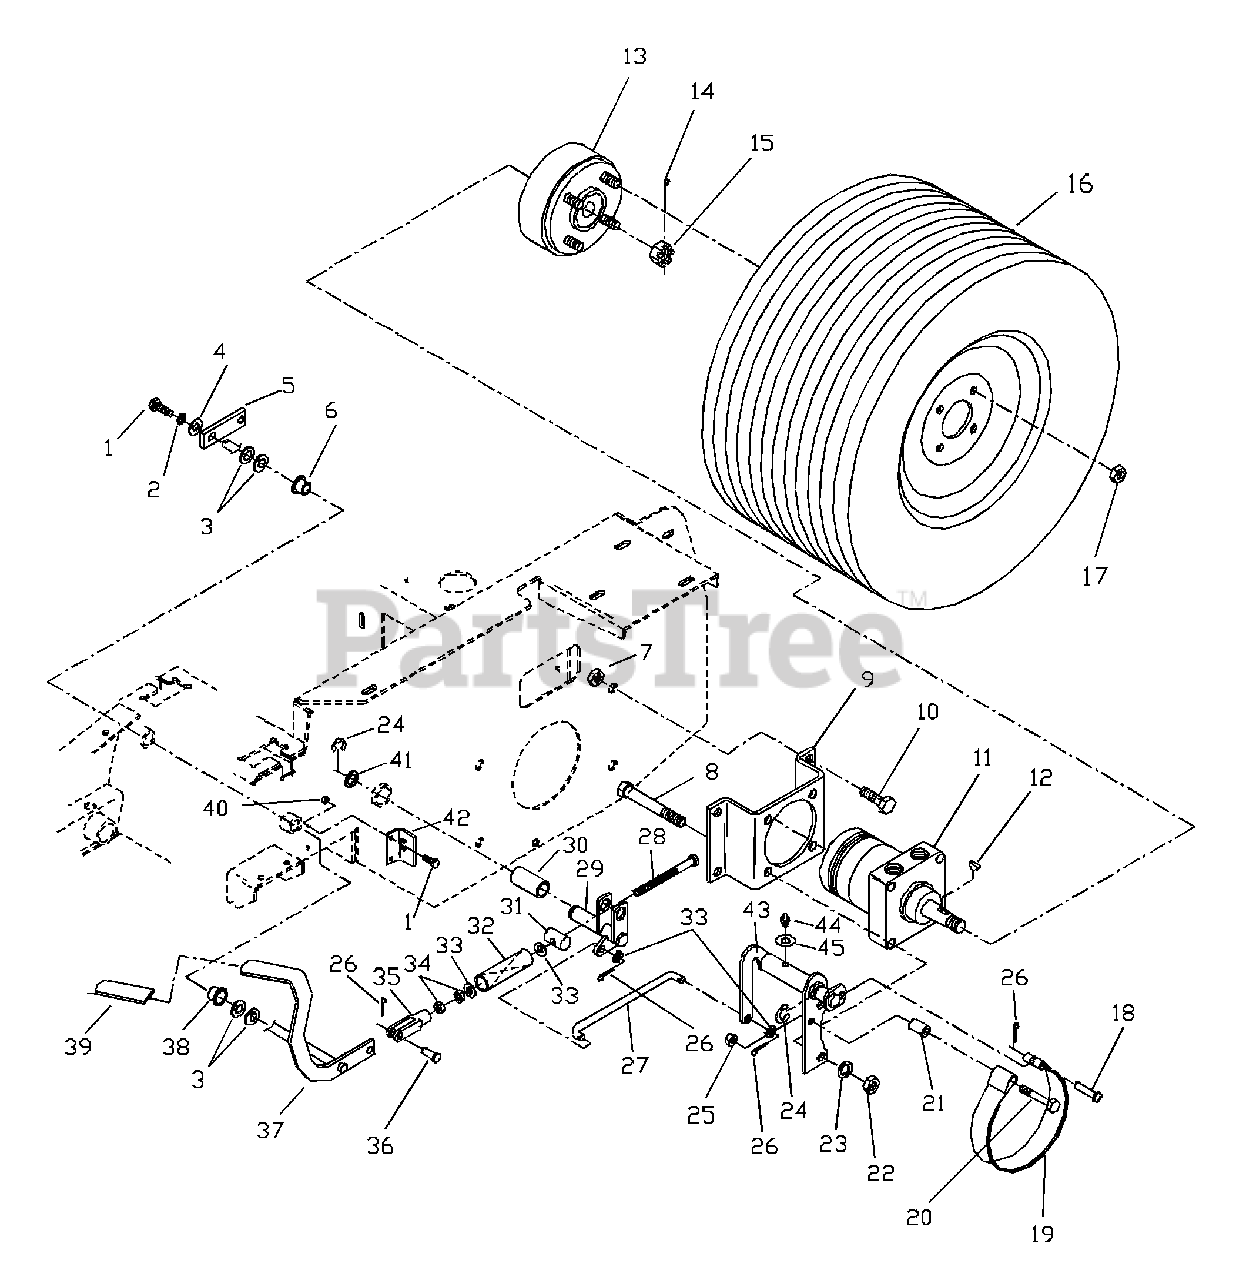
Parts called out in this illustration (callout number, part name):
1	HCS 1/4C X 3/4
2	1/4 LOCK WASHER
3	WASHER 7/16 SPRING
4	1 /4 FLAT WASHER
5	ARM, PARK BRAKE
7	NUT 1/2C NYLOC
8	HCS 1/2C X 2.75
9	MOTOR STANDOFF
10	HFCS 1/2C X 1.25
11	WHEEL MOTOR
12	WOODRUFF KEY
13	HUB W/ BRAKE DRUM
14	COTTER PIN
15	CASTLE NUT
16	REAR TIRE ASSEMBLY
17	LUG NUT 1/2F
18	3/8 X 1.50 CLEVIS PIN
19	BRAKE BAND
20	HCS 3/8C X 3 GD 8
23	1/2 LOCK WASHER
24	E - RING 3/4
25	NUT 3/8C CTR. LOCK
26	COTTER PIN
27	BRAKE LINKAGE LT
27	BRAKE LINKAGE RT.
28	HCS 3/8F SPECIAL
30	BRONZE BEARING
31	TRUNION PIN
33	3/8 SAE WASHER
36	3/8 X 1.125
37	BRAKE LEVER WLDMT.
40	1/4C LOCK NUT
41	MACH. BUSHING 3/4
43	LEFT BRAKE BKT
43	RIGHT BRAKE BKT
44	ZERK
